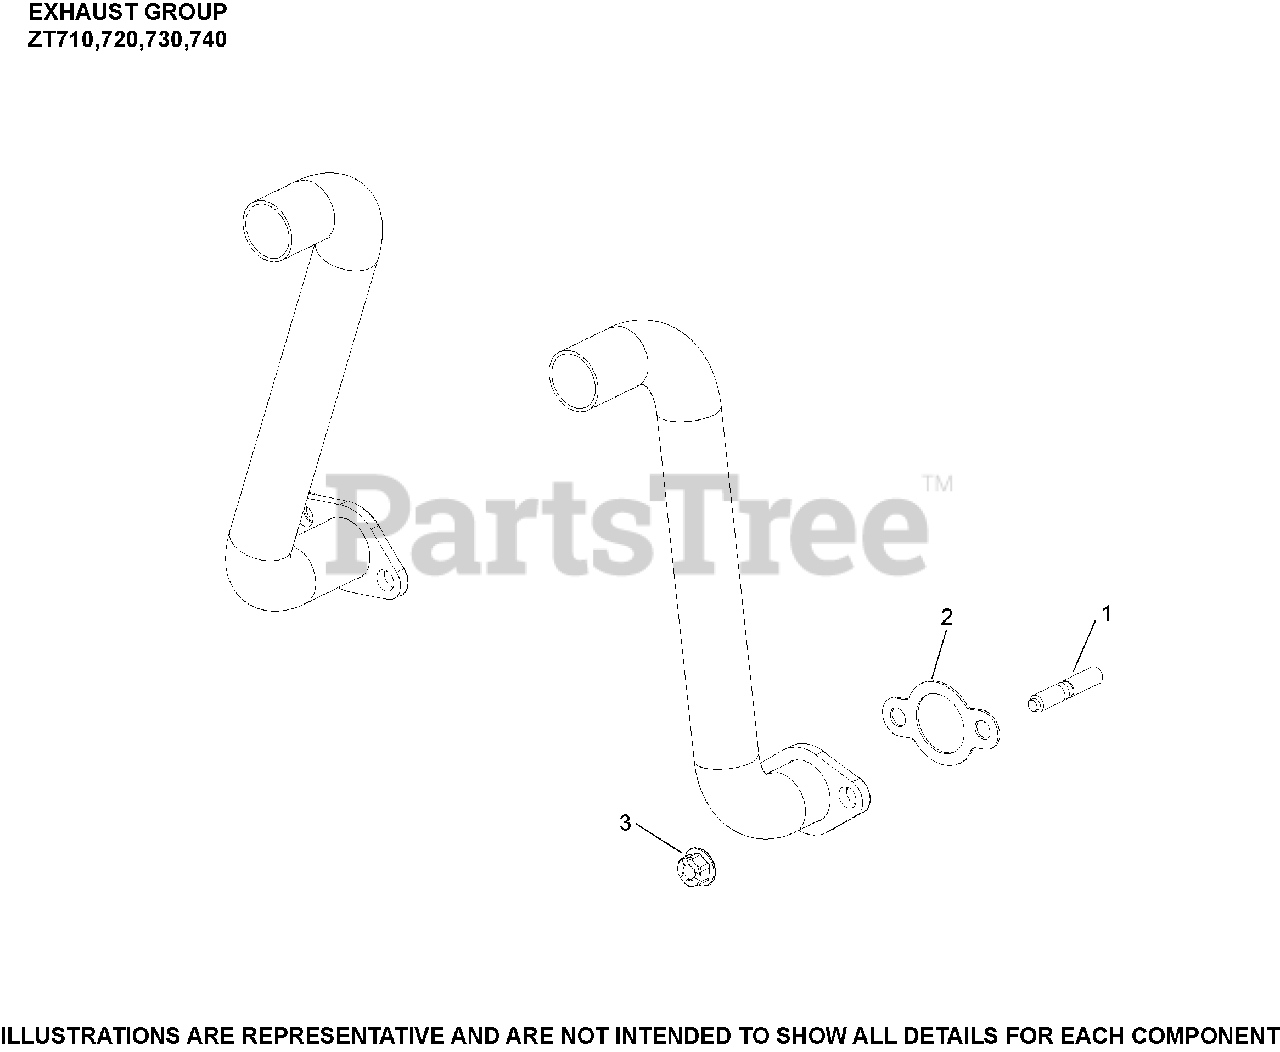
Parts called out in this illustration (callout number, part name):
1	STUD, EXHAUST USE 25 072 36-S
2	GASKET, EXHAUST
3	NUT, HEX FLANGE LOCK (M8)
